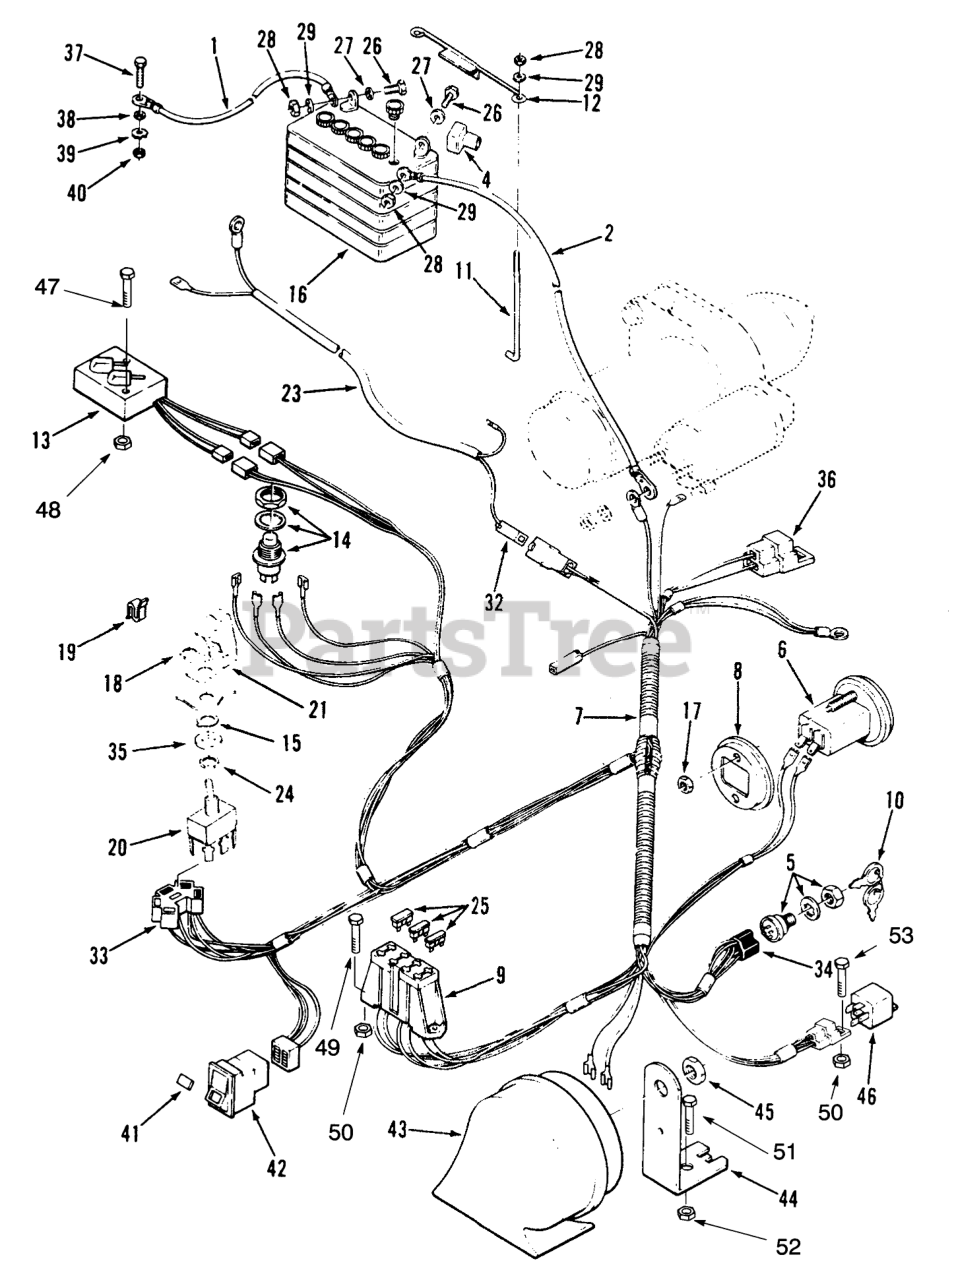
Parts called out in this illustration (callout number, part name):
1	WIRE -BLACK
2	ASS'Y-WIRE BATTERY
4	Boot
5	Switch-Ignition (Incl. Nut 101884 & Screw 103990)
6	Hourmeter (Incl. Ref. # 8)
7	Harness-Wiring (Incl. Ref.#9, 33, & 34)
8	CLAMP-HOUR METER
9	AUTO-FUSEBLOCK TERM
10	KEY-IGNITION
11	HOOK-BATTERY RETAIN
12	HOLDDOWN-BATTERY
13	SWITCH-ASS'Y NEUTRAL
14	SWITCH-PLUNGER
15	TAB-WASHER
16	Battery
17	NUT-HEX
19	CLIP-CABLE
20	SWITCH-TOGGLE, SEALED
21	COVER-PTO SWITCH
23	Harness-Wiring (Inc. Ref.#32)
24	NUT-HEX, SPECIAL
25	FUSE-BLADE, 15 AMP
26	SCREW-HH
27	WASHER-FLAT
28	NUT-WING
29	WASHER-LOCK
32	MALE CONNECTOR
33	Label-Emissions
34	CONNECTOR-5 WAY-SERV
35	WASHER
36	CONNECTOR BODY
37	SCREW-HH
38	WASHER-FLAT
39	WASHER-LOCK
40	NUT-HEX
41	LENS-ENG TEMP
42	Switch-Test (Incl. Ref.#41)
43	Horn And Bracket Assembly (Inc. Ref.# 44 & 45)
44	BRACKET-HORN
45	LOCKNUT
46	Relay
47	SCREW-PPH
48	NUT-KEPS
50	NUT-LOCK, NI
51	SCREW-HH
52	NUT-LOCK, NI
53	SCREW-SHWH
